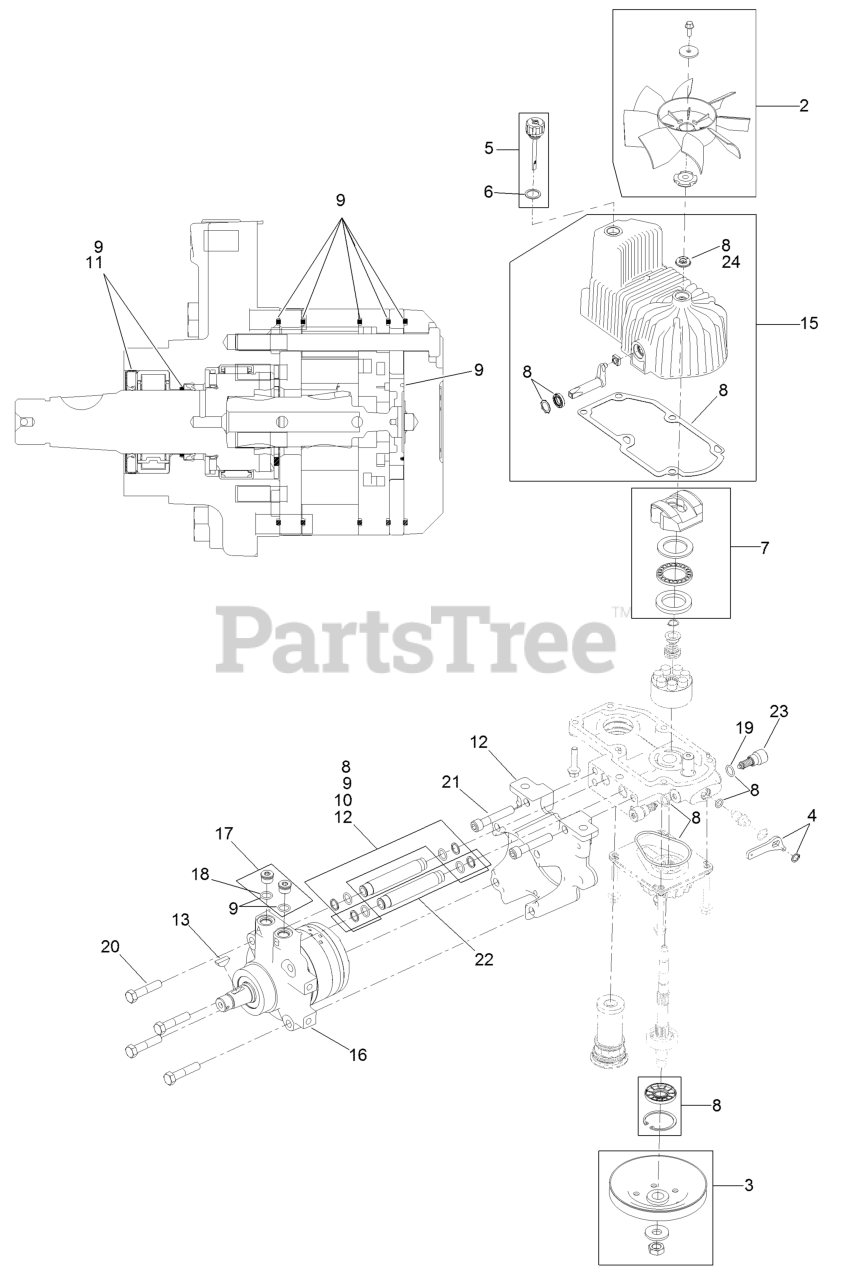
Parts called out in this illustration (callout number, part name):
2	Fan Kit
3	Pulley Kit
4	Handle-Bypass Valve, Hydro
5	Dipstick-Hydro W/Gasket
6	Gasket-Dipstick, Hydro
7	Swash Block Kit
8	Pump Seal Kit
9	Motor Seal Kit
10	Tube Seal Kit
11	Output Shaft Seal Kit
12	Nose Cup-Uht
13	Key-Woodruff
15	Housing-LH
16	Motor-Hydraulic LH 240Cc
17	Magnetic Plugs Service Kit
19	O-Ring-Check Valve
20	Screw HH
21	Screw-HSH
22	Hydraulic Tube Kit
23	Shock Valve, 12Cc Hydro
24	Seal-Fan Drive
99	Puller-Pulley
99	Flow Test Kit
